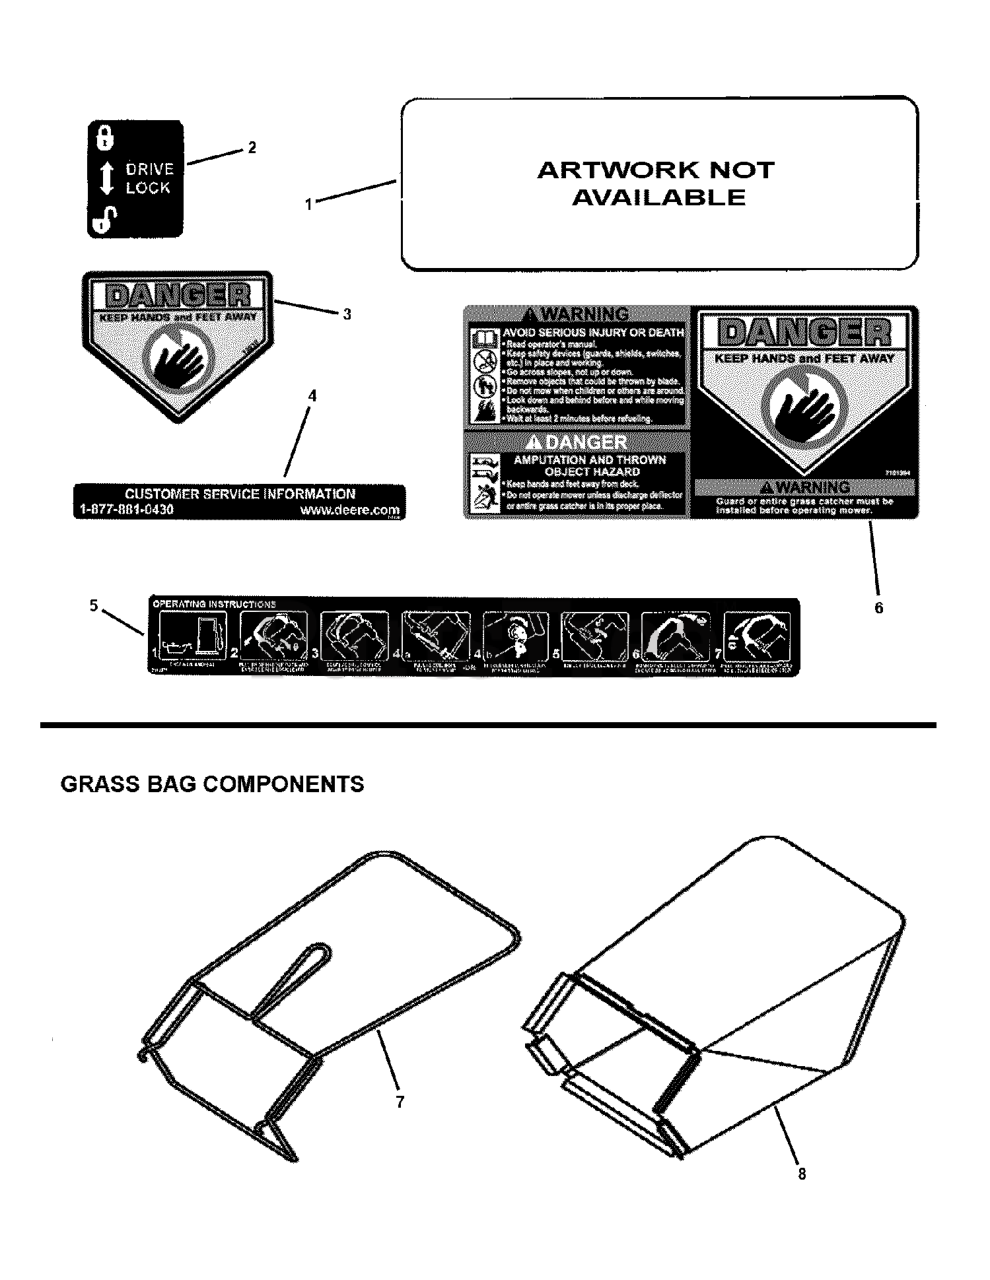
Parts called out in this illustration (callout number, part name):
1	DECAL, JS26 MOWMENTUM
2	DECAL, NEUTRAL LOCK
3	DECAL, DANGER, CUT FINGER
4	DECAL, CUSTOMER SERVICE, DEERE
5	DECAL, OPERATION, JD
6	DECAL, WARNING, REAR DISCHARGE DOOR
7	BAG FRAME, RD
8	BAG, GRASS, 22" REAR DISCHARGE
